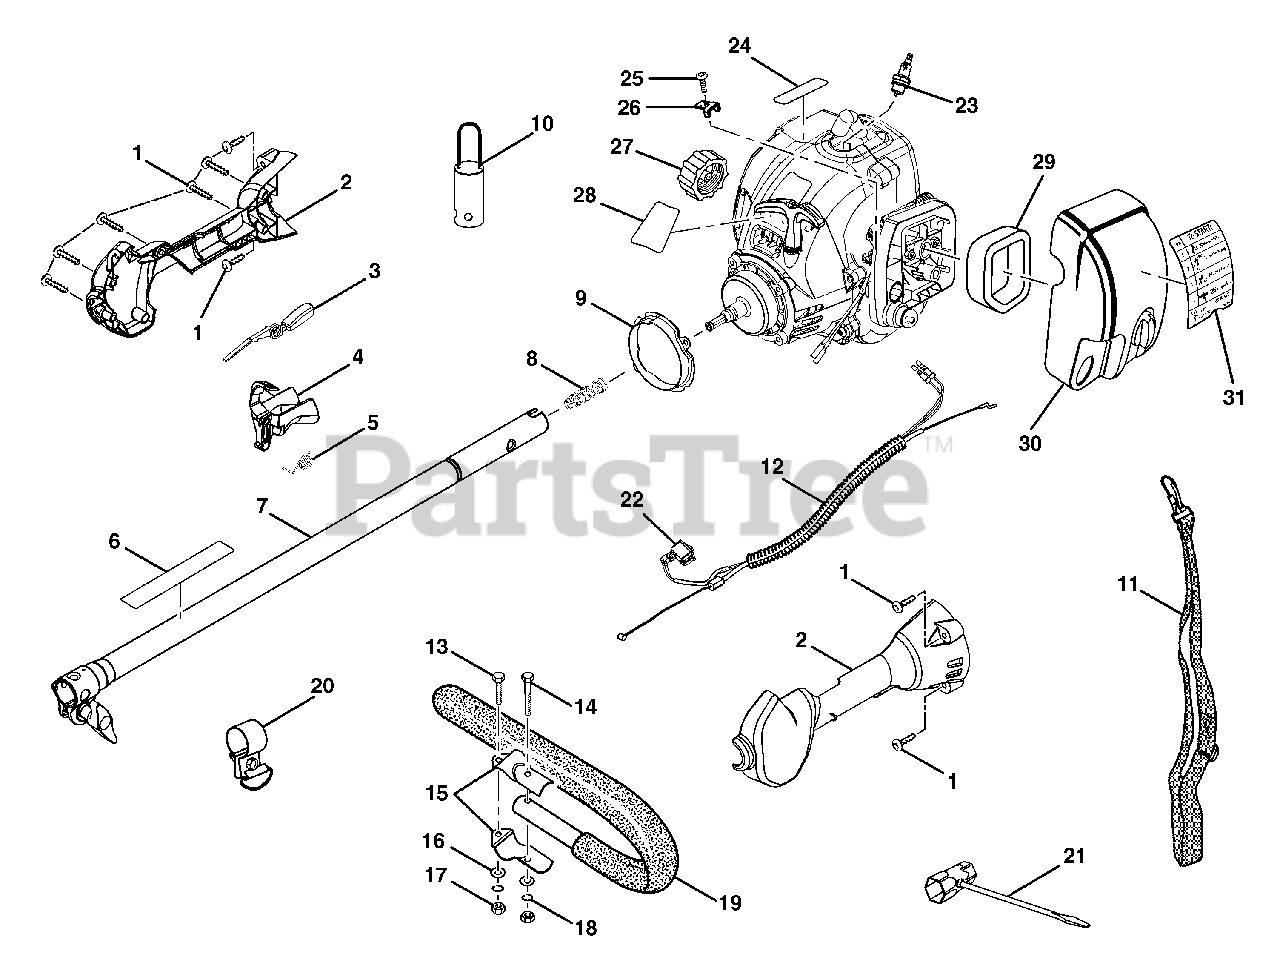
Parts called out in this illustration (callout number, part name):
1	SCREW (10-14 X 1 in. T.F. TRUSS HD)
2	HANDLE ASSEMBLY
3	TRIGGER LOCK
5	TORSION SPRING
6	WARNING LABEL
7	BOOM ASSEMBLY
8	COMPRESSION SPRING
9	RING GUARD
10	HANGER CAP
11	SHOULDER STRAP
12	THROTTLE AND LEAD ASSEMBLY
13	BOLT (1/4-20 X 1 in. HEX HD)
14	BOLT (1/4-20 X 1-1/2 in. HEX HD)
15	HANDLE BAR CLAMP
16	WASHER
17	HEX NUT (1/4-20)
18	LOCK WASHER
19	J HANDLE AND GRIP
20	STRAP HANGER
21	COMBINATION WRENCH
22	SWITCH (MOMENTARY CONTACT)
23	SPARK PLUG (CHAMPION RCJ6Y OR NGK BPMR7)
24	LOGO LABEL
25	SCREW(M4 X 16 mm TORX PAN HD)
26	THROTTLE CABLE CLIP
27	FUEL CAP ASSEMBLY
28	MODEL LABEL
29	AIR FILTER
30	AIR BOX COVER
31	STARTING/PRIMER LABEL
